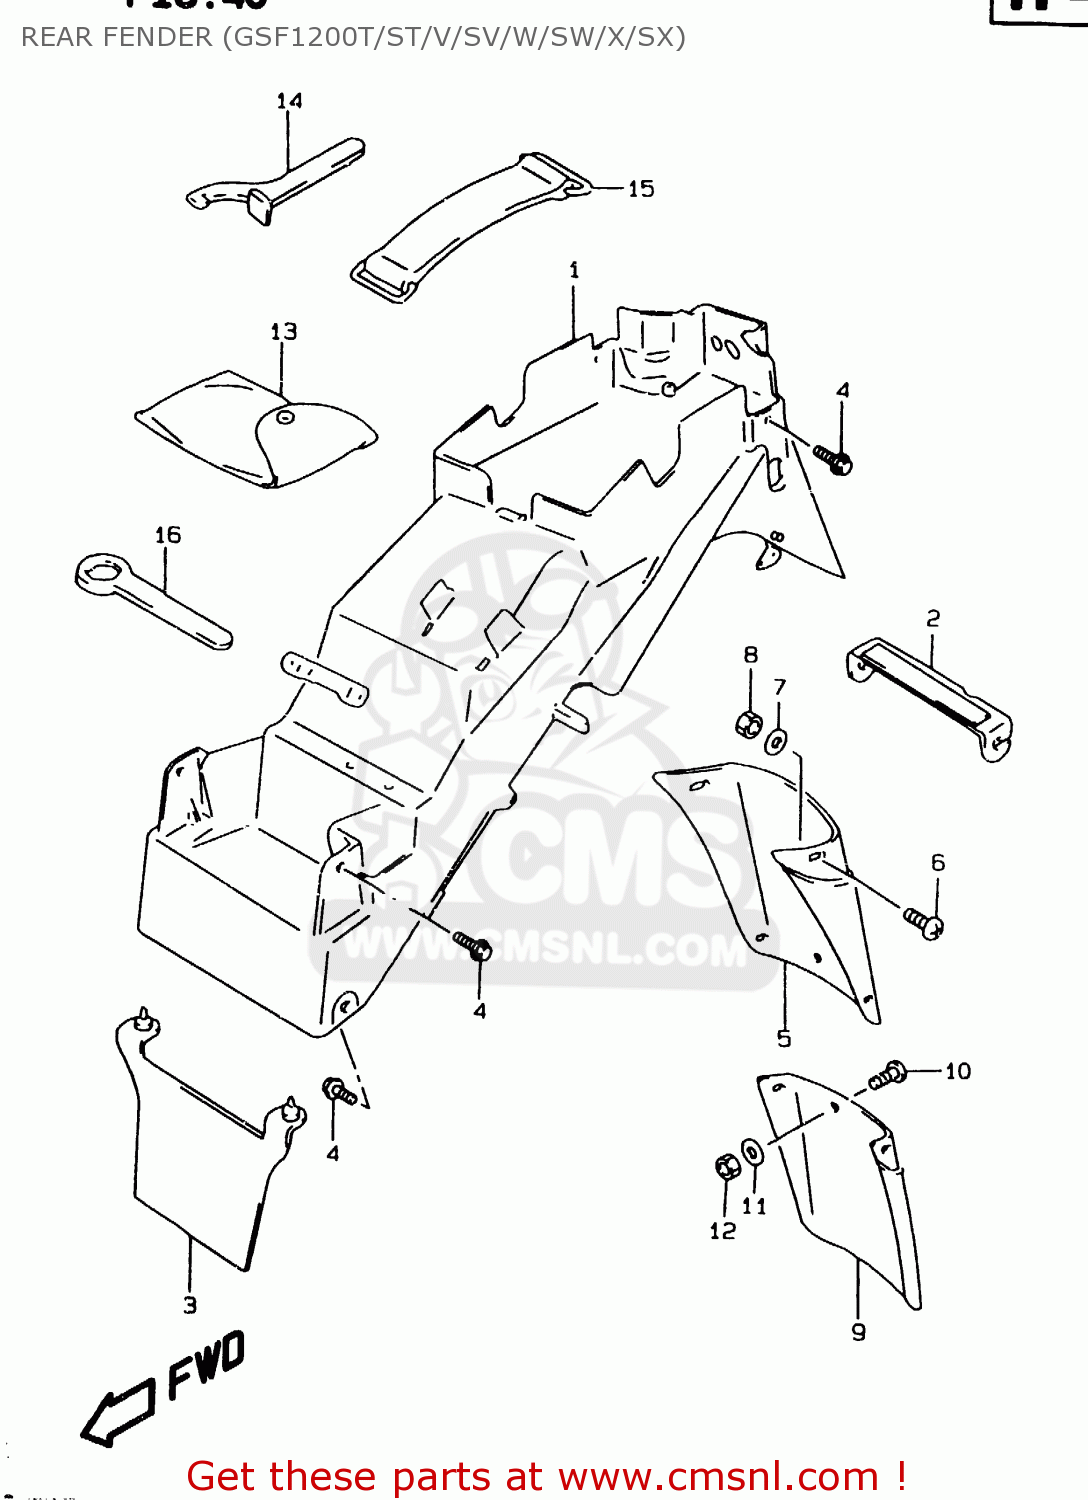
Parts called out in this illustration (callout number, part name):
1	FENDER, REAR
2	REINF,RR FENDER
3	MUDGUARD,RR FENDER FR
4	BOLT(6X16)
5	EXTENSION,RR FENDER
6	SCREW
7	WASHER(6.5X18X1.6)
8	NUT 6MM
9	MUDGUARD,RR FENDER EXTENSION
10	SCREW
11	WASHER(6.5X18X1.6)
12	NUT 6MM
13	TOOL ASSY
14	CLAMP
15	BAND
16	RING,SPANNER(24)
